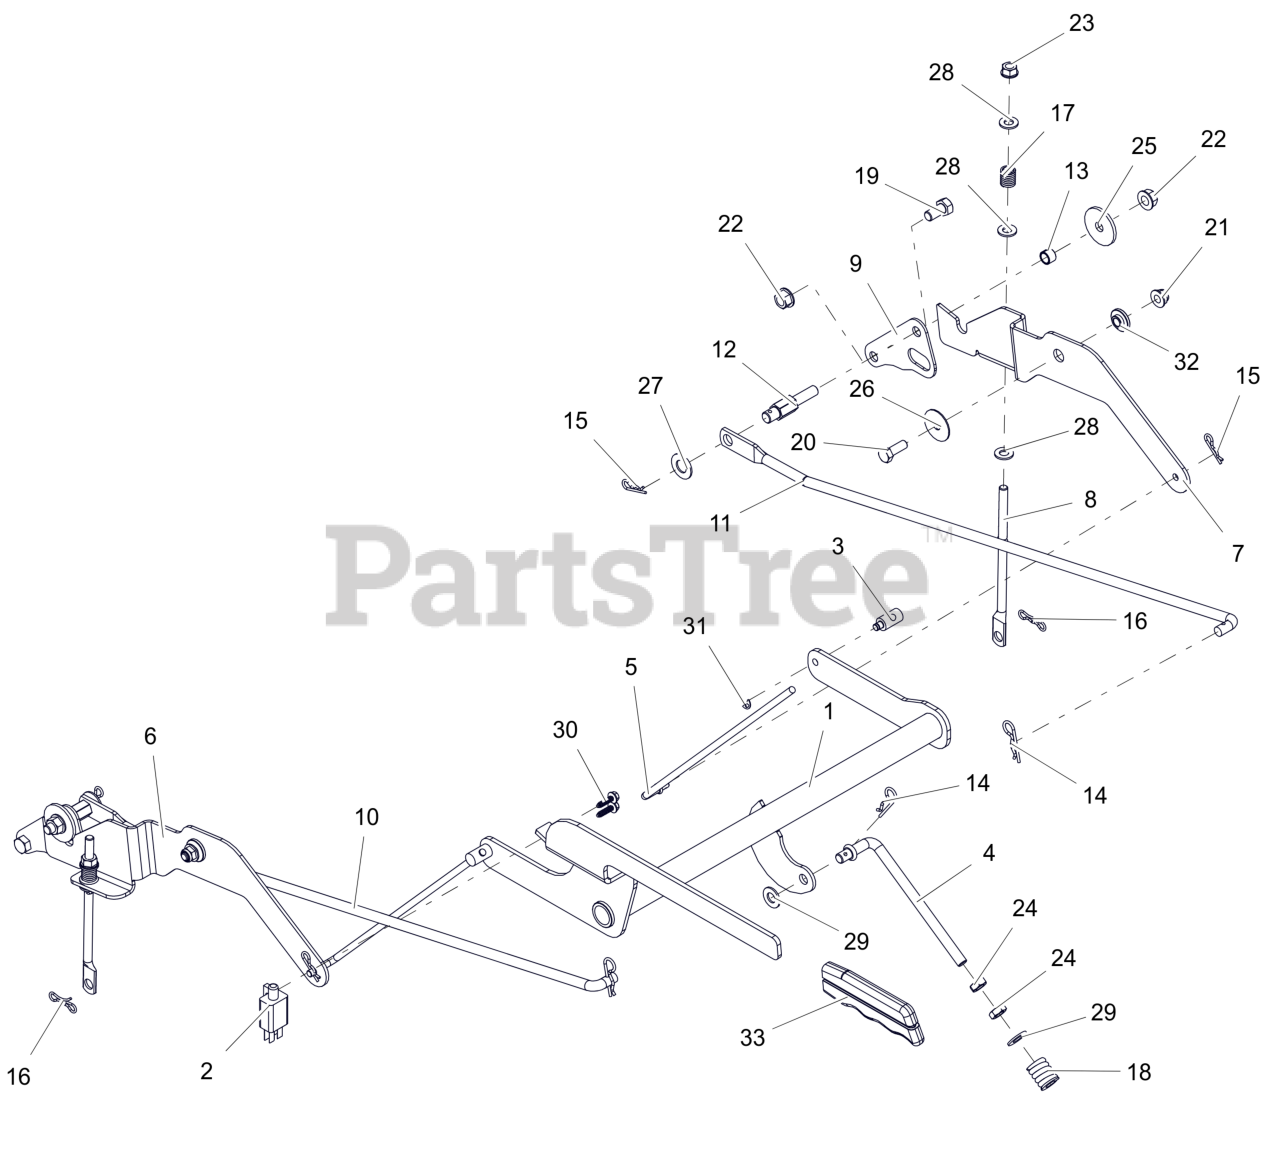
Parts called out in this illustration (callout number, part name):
1	WLDMT, BRAKE LEVER
2	SWITCH- DOUBLE POLE N.O./N.O.
3	TRUNION, 1/4-20
4	LINK, OVER CENTER, PARKING BRK
5	LINK, BRAKE ARM
6	INTERLOCK, RH BRAKE LINK
7	INTERLOCK, LH BRAKE LINK
8	LINK, BRAKE COG
9	PLATE, TRANSAXLE ADAPTOR
10	LINKAGE, STEERING - RH
11	LINKAGE, STEERING - LH
12	POST, STEERING LINK MOUNTING
13	SPCR, SLV .385X.500X.350
14	PIN, HAIR #203 .09X1.50 ZCC
15	PIN, HAIR #213 .08X1.19 ZCC
16	PIN, BOWTIE #72 ZCC
17	SPRING, COMPRESSION
18	SG-COMP .187X.56X1.62
19	BLT,HEX .38-16X.75 G5 ZCC
20	BLT, HEX .31-18X.875 G5 ZCC
21	NUT,LK-NYL-FLG .31-18 G5ZC120
22	NUT-LK-CTR-FLG .375-16 GF ZCC
23	NUT,LK-CTR-FLG .31-18 GF ZCC
24	NUT-JAM .375-16 G2 ZCC
25	WSHR, FLT .380X1.50X.125 ZCC
26	WSHR, FLT .347X1.254X.048 ZCC
27	WSHR, FLT .505X1.00X.062 ZCC
28	WSHR,FLT .344X.688X.065 ZCC
29	WSHR,FLT .406X.812X.065 ZCC
30	SCR, PLASTITE #12X.75 ZCC
31	RG-RTNG-EXT .250X.025
32	BSHG, FLG .325X.499X.26X.88
33	GRIP, PARKING BRAKE (GREY)
